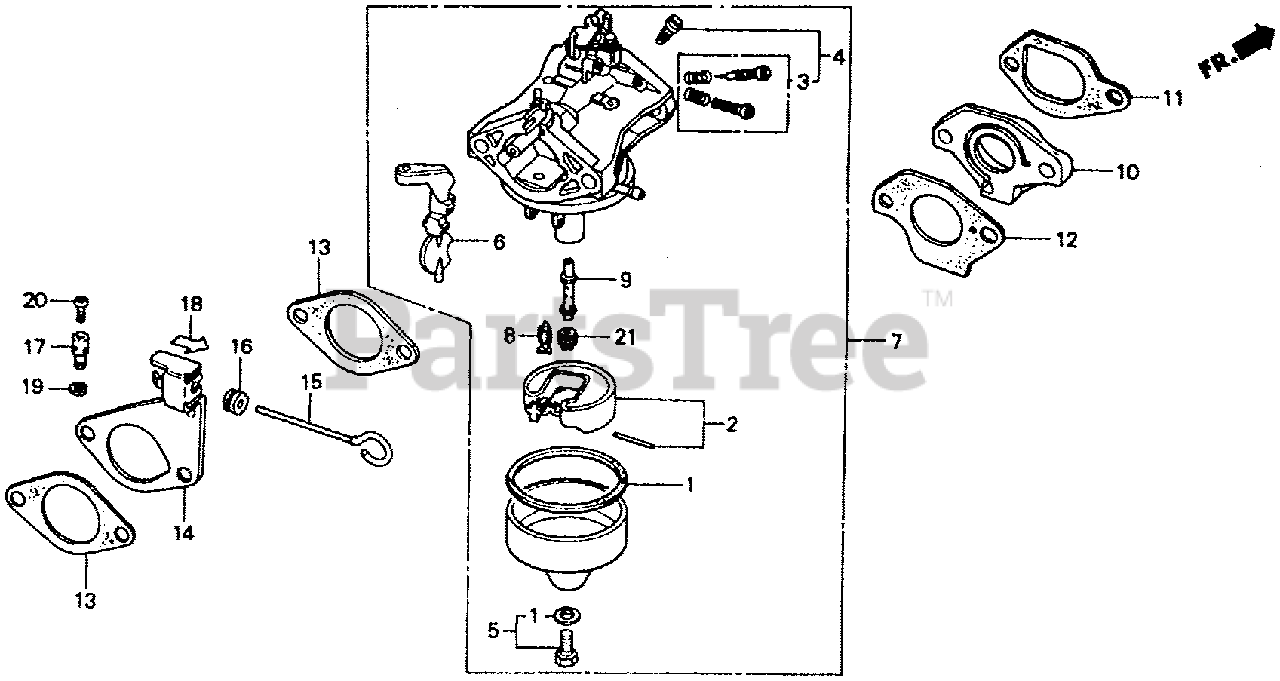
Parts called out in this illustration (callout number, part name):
1	GASKET SET
2	FLOAT SET
3	SCREW SET A
4	SCREW SET A (NOT AVAILABLE)
5	SCREW SET B
6	CHOKE SET
7	CARBURETOR ASSY.
8	VALVE, FLOAT
9	NOZZLE, MAIN
10	INSULATOR, CARBURETOR
11	GASKET, INSULATOR
12	GASKET, CARBURETOR
13	GASKET, AIR CLEANER
14	STAY, CHOKE CONTROL
15	ROD, CHOKE CONTROL
16	GROMMET, CHOKE ROD
17	HOLDER, CABLE
18	MARK, CHOKE
19	CIRCLIP (5MM)
20	SCREW, PAN (4X8)
21	JET, MAIN (#75)
21	JET, MAIN (#78)
21	JET, MAIN (#80)
21	JET, MAIN (#82)
21	JET, MAIN (#85)
